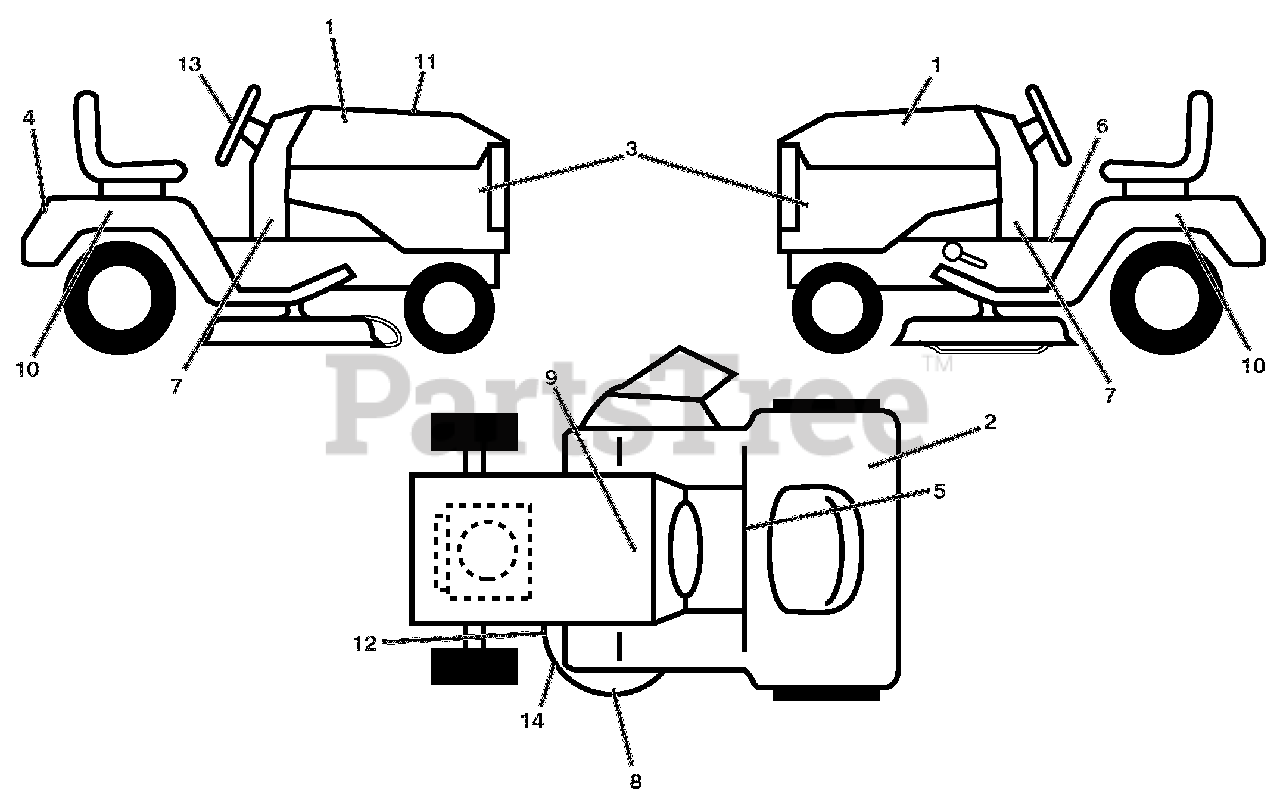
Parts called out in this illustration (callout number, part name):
1	DECAL.HOOD.RH.PRECISION.ARIENS
2	Decal Fender Service
3	DECAL.SDPNL.PWRDBY KOHL.ARIENS
4	DECAL.FENDER.REAR.ARIENS
5	Decal, Flag
6	DECAL.FENDER.WARNING.ENG/FR.07
7	DECAL.DASH.LOWER
8	DECAL.MOWER.CAUTION.TENSION.AR
9	DECAL.BAT.DAN/POI P/L SYM.WPN
10	DECAL.FENDER.SIDE.HYDRO.ARIENS
11	DECAL, REPLACEMENT
12	DECAL.MOWER.WARN.KEEP HAND AWY
13	DECAL.WHEEL.STEER.ARIENS
14	DECAL.V-BELT.SCH.42/46"MEC/ELE
